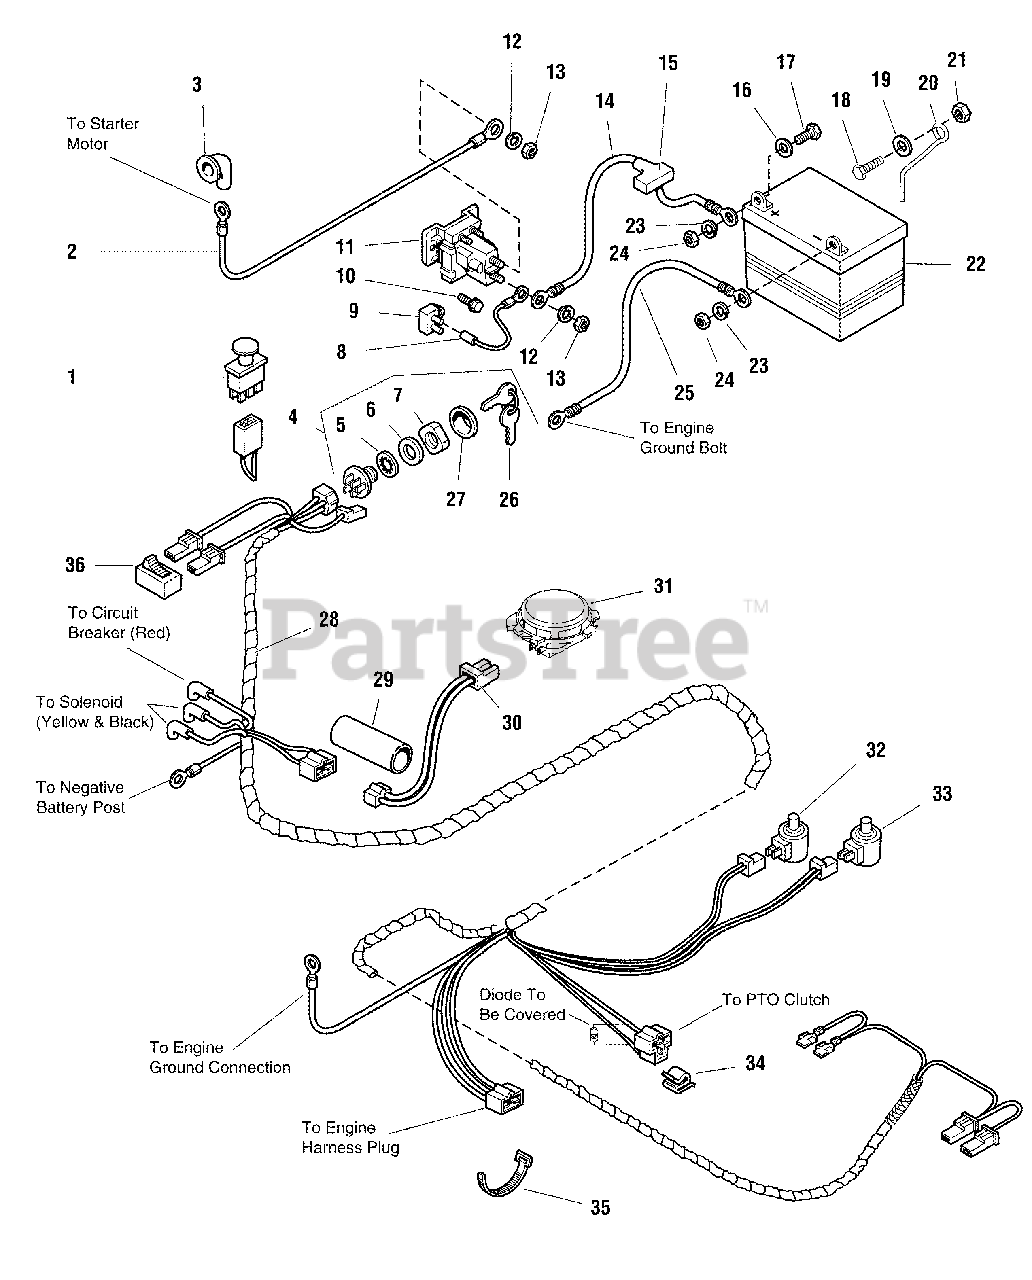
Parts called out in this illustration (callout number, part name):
1	SWITCH, PTO, Push/Pull
2	CABLE, # 6, 42-1/2 Long
3	COVER, Terminal
4	SWITCH ASSEMBLY, Ignition, 6 Pin (Includes Ref. Nos. 5, 6, 7, 26 & 27)
5	LOCKWASHER, Internal Tooth, 5/8
6	WASHER, 5/8
7	NUT, Hex Flange, 5/8-32
8	WIRE, 12GA, 5.9 Long Red
9	BREAKER, Circuit 12Volt, 20Amps W/Tab
10	SCREW, Hex Washer Head Taptite, 1/4 x 5/8
11	SOLENOID, 4 Pole12Volt DC
12	LOCKWASHER, External Tooth, 5/16
13	NUT, Hex, 5/16-24
14	CABLE, # 6, 10 Long
15	BOOT, Insulator Battery Terminal
16	WASHER, 1/4
17	CAPSCREW, Hex Head, 1/4 x 3/4
18	CAPSCREW, Hex Head, 5/16-18 x 3/4
19	WASHER, 5/16
20	ROD, Battery Hold Down
21	NUT, Hex Lock ESNAL, 5/16-18
22	BATTERY, 12 Volt
23	LOCKWASHER, 1/4
24	NUT, Hex, 1/4-20
25	CABLE, # 6, 52-1/2 Long
26	KEY, Ignition
27	COVER, Ignition Switch
28	WIRE ASSEMBLY, Main Harness
29	SHRINK TUBE
30	WIRE ASSEMBLY, 16GA, 16 Long
31	SWITCH, Seat, Gray Switch, Gray Retainer
31	SWITCH, Seat, Gray Switch, Black Retainer
32	SWITCH, Push, Black
33	SWITCH, Push, Grey
34	CLIP, Wire
36	SWITCH, Headlights
